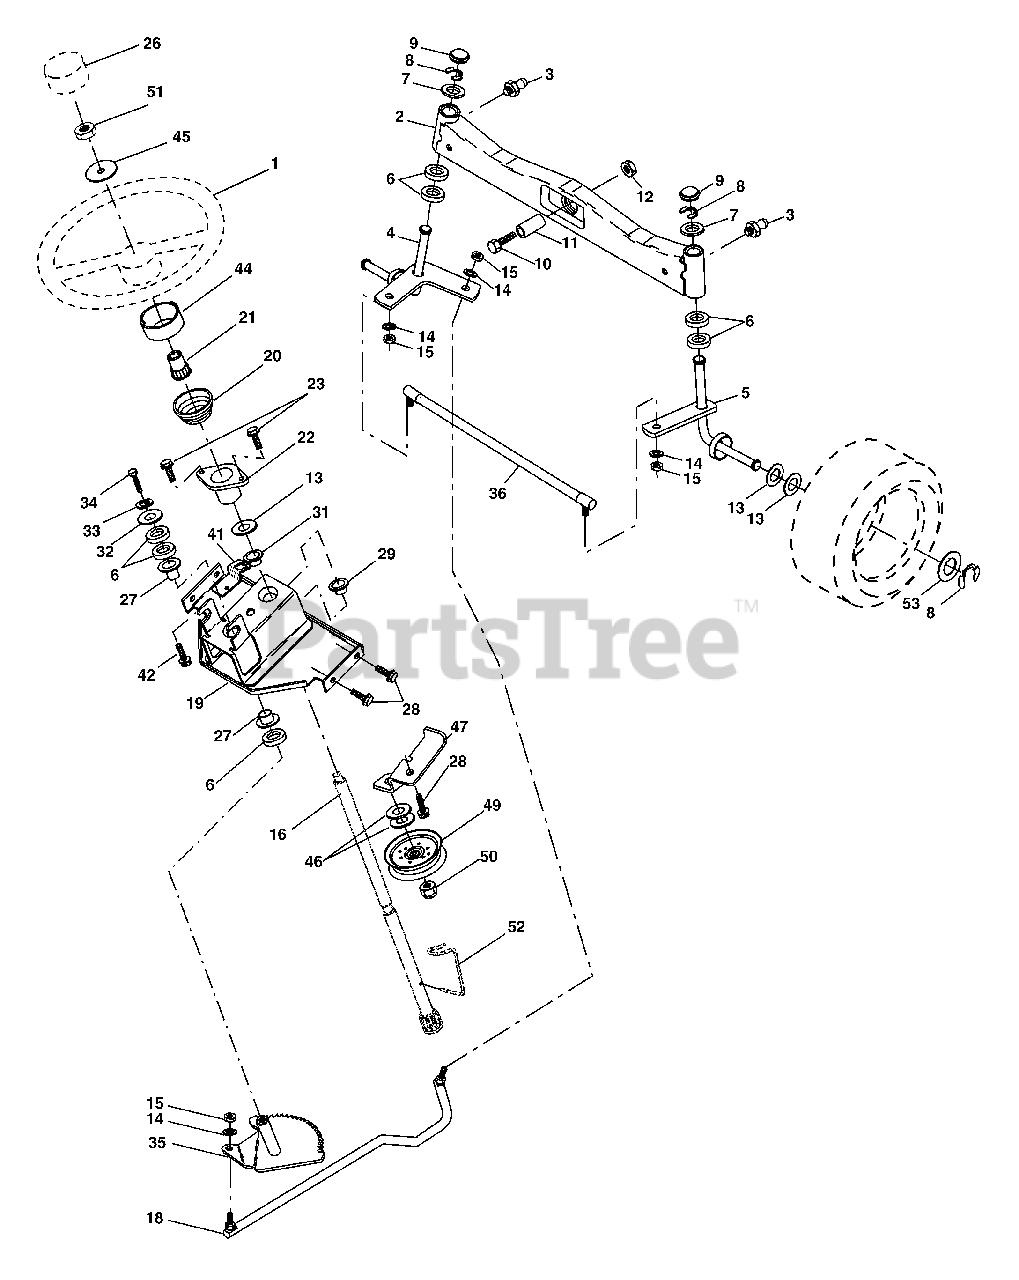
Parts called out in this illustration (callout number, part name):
1	Wheel, Steering
2	Axle Asm., Front
3	Fitting, Grease
4	Spindle Asm, LH
5	Spindle Asm., RH
6	Bearing, Race Thrust Harden
7	Washer 25/32 x 1-5/8 x 16 Ga.
8	Ring, Klip #T5304-75
9	Cap, Spindle
10	Bolt, Fin Hex 5/8-11 x 2-3/4
11	Spacer, Brg. Axle Front
12	Nut, Lock Flange 5/8-11 unc
13	Washer 25/32 x 1-1/4 x 16 Ga.
14	Washer, Lock Hvy Hlcl Spr 3/8
15	Nut Crownlock 3/8-24
16	Shaft Asm., Steering
18	Draglink
19	Support Asm., Steering Vgt
20	Boot Steering Stealth
21	Adapter, Wheel Steering
22	Bushing, Strg.
23	Screw
26	Insert Cap Strg WH
27	Bearing, Col. Strg.
28	Screw Hexwsh thdr 3/8-16 x 3/4
29	Bearing, Flange
31	Bushing, Nyliner Snap
32	Washer 11/32 x 1 x 10 Ga.
33	Washer, Lock Hvy Hlcl Spr 5/16
34	Bolt, Hex Hd 5/16-18 x 3/4
35	Gear, Sector Steering
36	Tie Rod
41	Bracket Switch Interlock Vgt 97
42	Screw Thdrol 5/16-18 x 1/2 Tyt
44	Extension Steering
45	Washer 9/16 x 1-1/2 x 11 Ga.
46	Washer 13/32 x 1 x 10 Ga.
47	Bracket Asm. Idler Stationary
49	Pulley Idler Flat
50	Nut Lock Flg. 3/8-16 unc
51	Nut Hex Jam Toplock 1/2-20 unf
52	Clip Steering
53	Washer Hardened
